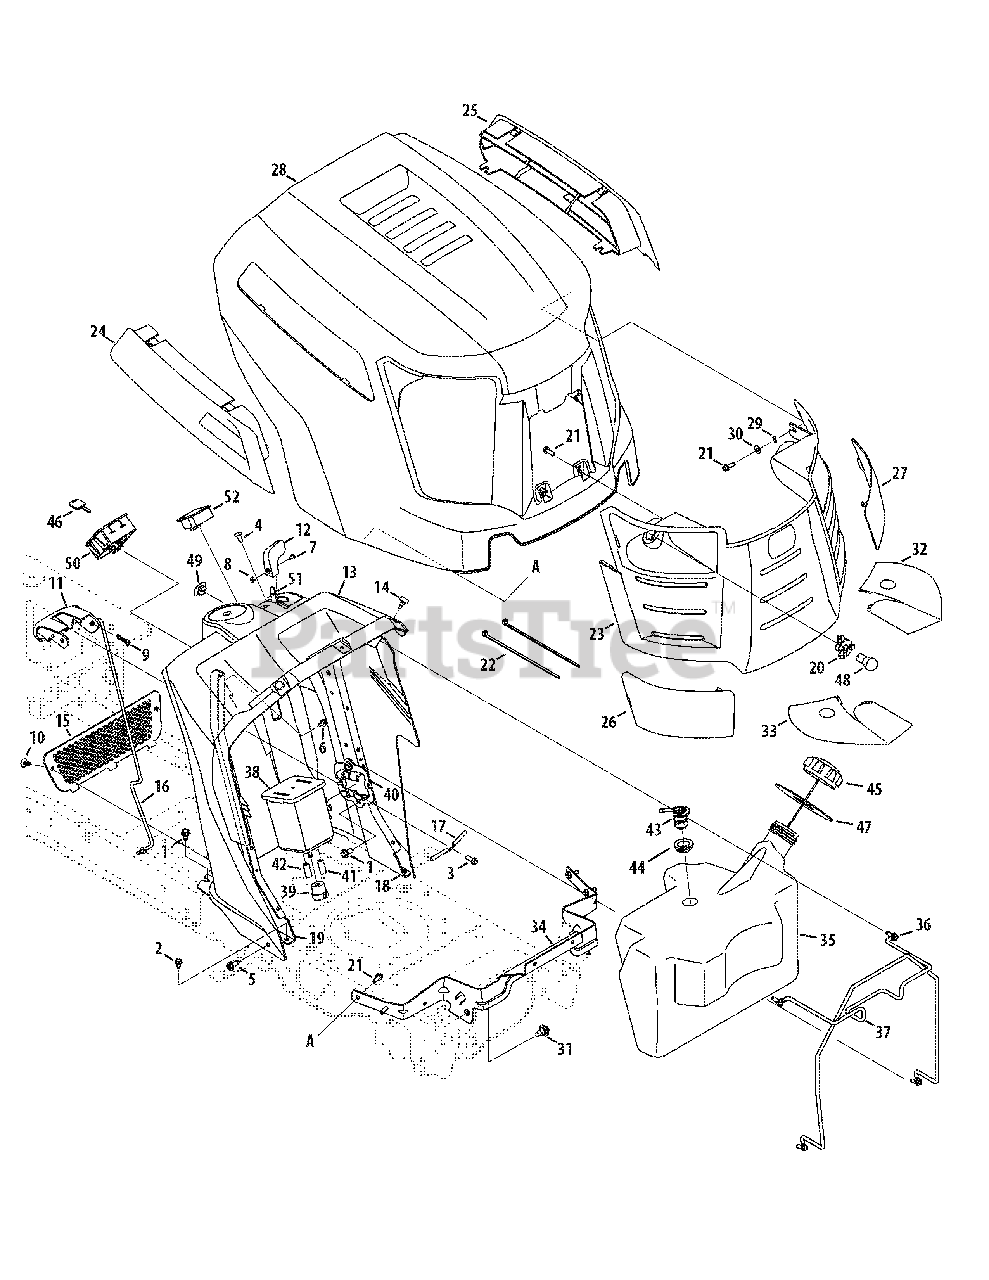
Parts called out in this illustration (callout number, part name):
1	Screw, Self-tapping, 5/16-18, .750
2	Screw, Self-tapping, 1/4-20, 0.500
3	Screw, HL, 1/4-15, 0.750
4	Screw, Ab, 1/4-14, 0.625,
5	Screw, Self-tapping, 5/16-18, 0.750,
6	Screw, Self-tapping, 1/4-20 x .625
7	Screw, Mach, #8-32, 0.375
8	Nut, Hex, #8-32
9	Pin, Cotter, Bow-Tie 72
10	Clip, Ratchet, .250 Dia
11	Lever, Dash, Cruise/Brake
12	Knob, Throttle
13	Dash Panel, A-Style, NO LGT SW
14	Bumper, .62 Dia X .3
16	Rod, Control, Latch Cub
17	Rod, Lever, Bent
18	Support, Dash, Plate LH
19	Support, Dash, Plate RH
20	Socket, Lamp
21	Screw, 1/4 Dia, .750
22	Tie, Cable, Push Mount 7.5 Lg
23	Grille Ass’y (Incl. 26, 27, 32 & 33)
24	Scoop, Hood, RH A-Style
25	Scoop, Hood, LH A-Style
26	Lens, Hood, RH A-Style
27	Lens, Hood, LH A-Style
28	Hood, A-Style
29	Washer, Lock, 1/4, External
30	Washer, Flat, .271, .630, .065
31	Screw, Shoulder, .43x.29, 5/16-18
32	Reflector, Cub A Style, LH
33	Reflector, Cub A Style, RH
34	Bracket, Pivot, Hood A-Style
35	Tank, Fuel, 3.75 Gal.
35	Tank, Fuel, 3.30 Gal. (California)
36	Screw, Self-tapping, 1/4-20, .625
36	Screw, Self-tapping, 1/4-20, .75 (California)
37	Rod, Support, Fuel Tank
38	Cnstr, Carbon, 5 Gallon (California)
39	Filter, Vent, Canister (California)
40	Bracket, Adapter, Canister (California)
41	Hose, Fuel, Low Perm, 3/16 Wht (California)
42	Hose, Fuel, Low Perm, 7/32 Yel (California)
43	Valve, Rollover Grommet (California)
44	Grommet, Rubber, 23.0 ID (California)
45	Cap, Fuel
45	Cap, Fuel (California)
46	Key, Ignition
47	Gasket, Fuel Tank
48	Lamp, 12v
49	Plug, Choke
50	Module Switch, Ignition
51	Cable, Throttle/Choke, 28"
52	Meter, Indicator
